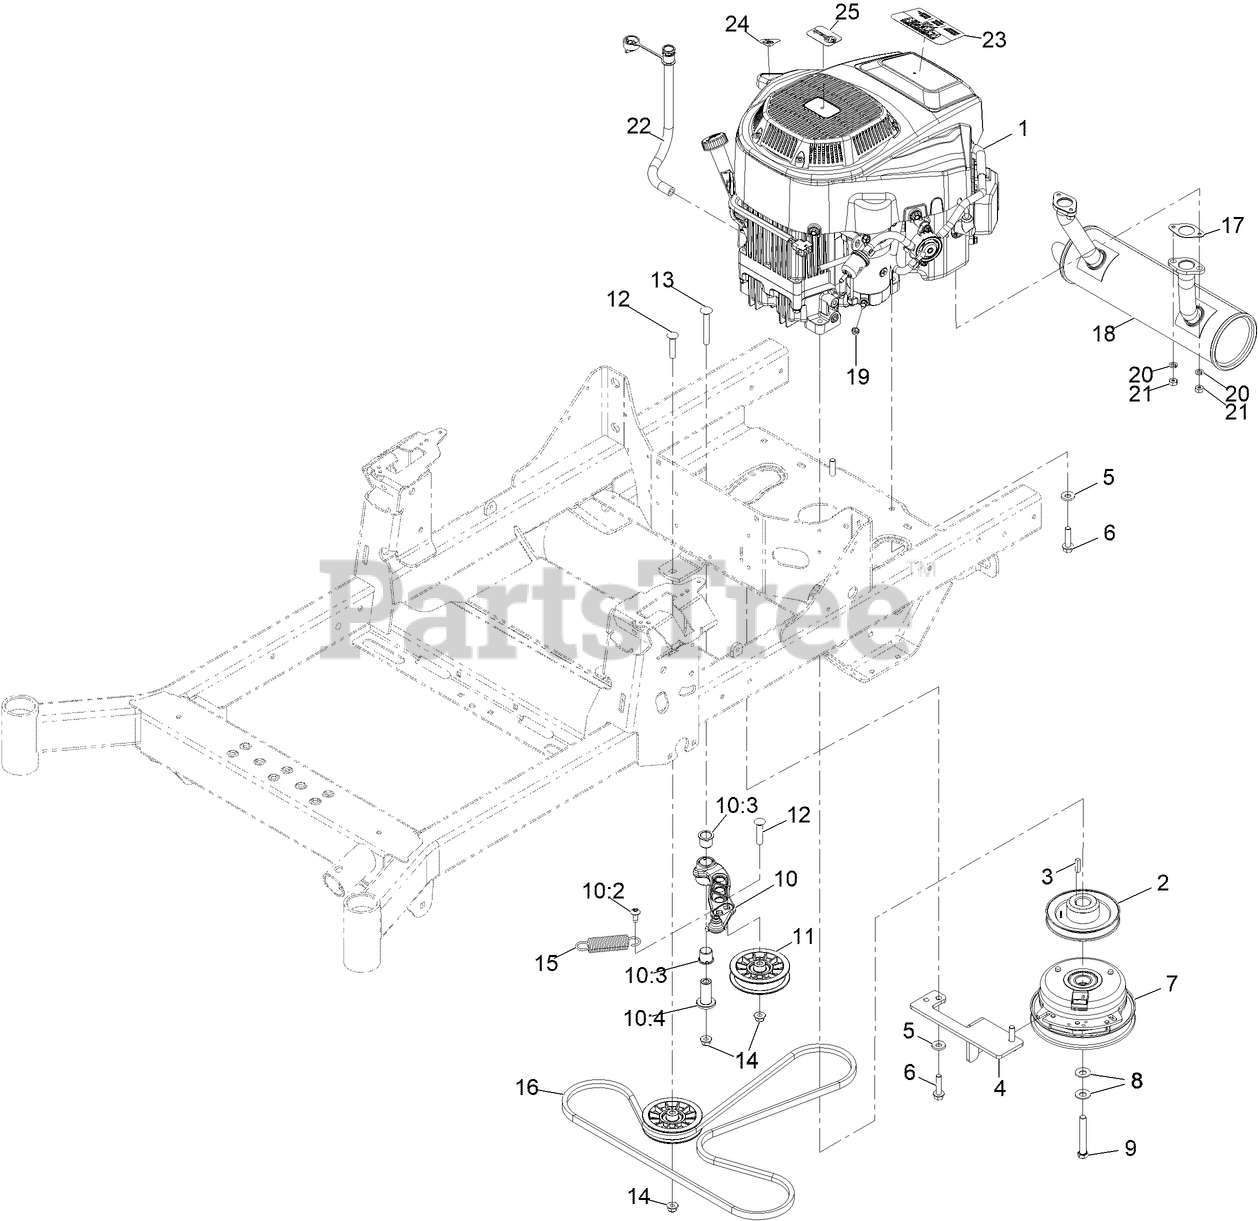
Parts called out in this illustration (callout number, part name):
1	ENGINE-2P77F
2	SHEAVE, ENGINE
4	Anchor-Clutch
5	WASHER-BELLEVILLE
6	SCREW-HWH
7	CLUTCH 1.00
8	WASHER-SPRING
9	SCREW-HH W/LOCTITE
10	ASM, PUMP IDLER
10:2	SCREW, TAPTITE
10:3	BUSHING, IGUS
10:4	Spacer, Idler Pivot
11	PULLEY-FLAT IDLER
12	SCREW-CARR
13	SCREW-CARR
14	NUT-HF, NI
15	SPRING-EXTENSION
16	BELT-V
17	GASKET-EXHAUST
18	MUFFLER, LONCIN
20	WASHER-LOCK, SPLIT
22	OIL DRAIN SERVICE KIT
23	DECAL-ENGINE 708 V-TWIN EXMARK
24	DECAL-DRAIN, OIL
